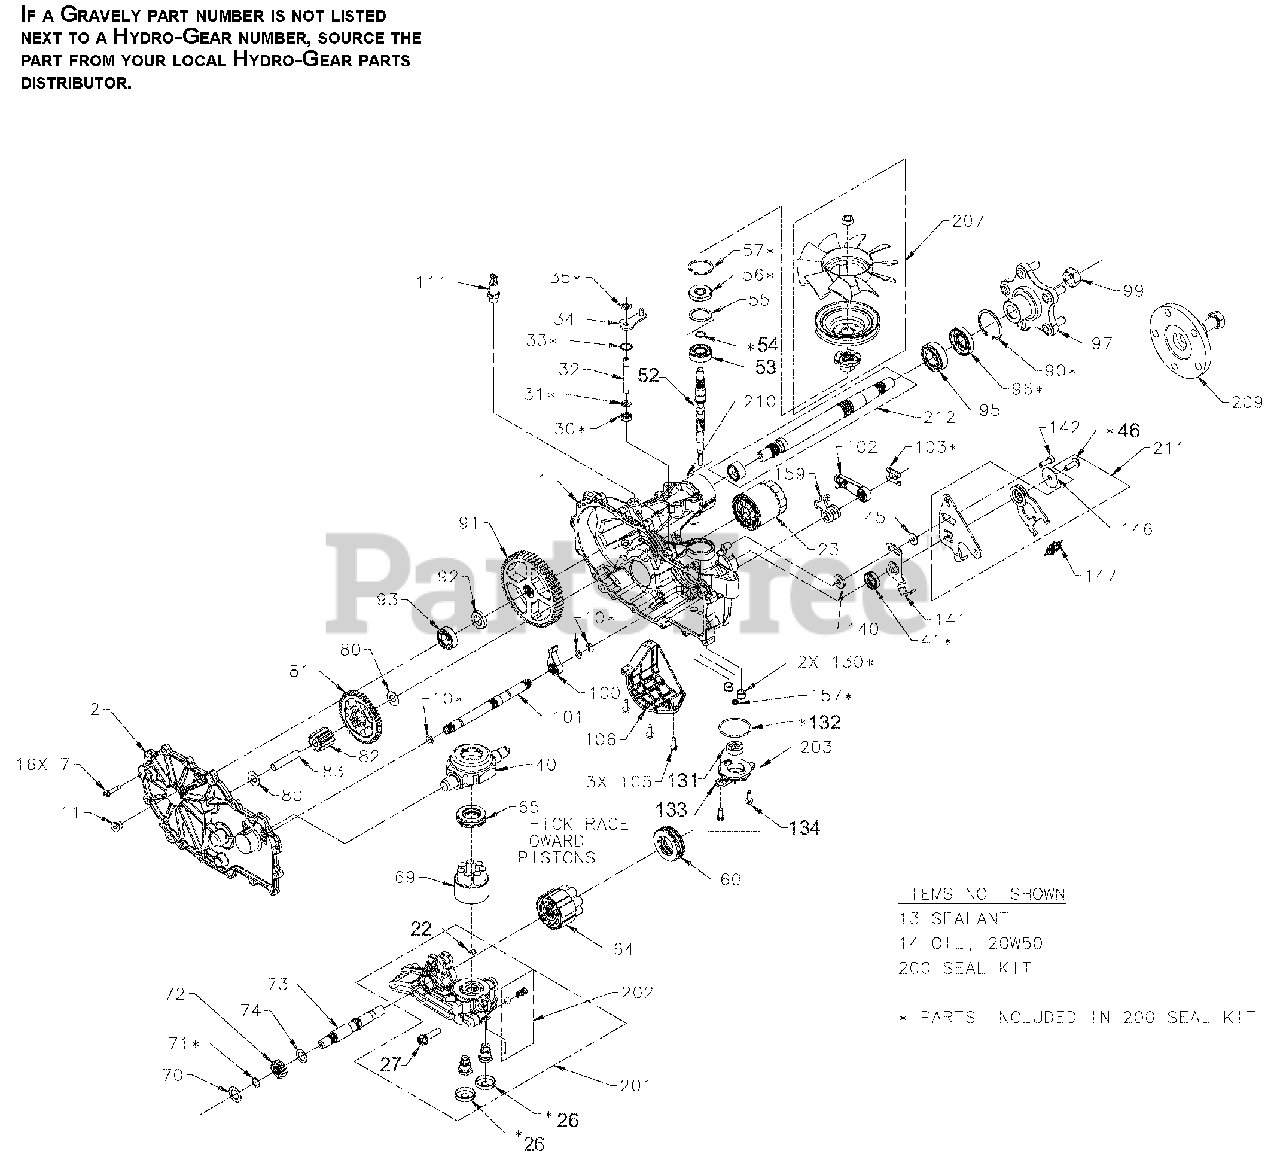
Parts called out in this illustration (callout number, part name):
7	HFHCS 1/4-20 x 1.25
11	Plug, 9/16-18 (Metal)
22	Plate, Bypass
23	Filter, Oil
26	Seal, Plug 1.25 x .25
30	Seal, Lip .375 x .75 x .25
31	Ring, Retention .375 External
33	Ring, Retention .750 Internal
34	Arm, Bypass
35	Ring, Retention .375 Ext
40	Trunnion, Swashplate
41	Seal, LIP 18 x 32 x 7
45	Washer, .34 x .88 x .06
46	TWHCS 5/16-24 x 1.00
53	Bearing, Ball 17 x 40 x 12 Open 6203
54	Ring, Ret Wire .561 ID
55	Washer, 1.23 x 1.56 x .04
56	Seal, Lip 17 x 40 x 7
57	Ring, Ret 1.59 Int
60	Bearing, Thrust
64	Assembly, Cylinder Block, 16cc
65	Bearing, Thrust Ball 30 x 52 x 13
69	Assembly, Block, 7 Piston
70	Washer, .63 x 1.0 x .05
71	Ring, Retaining .625
74	Washer, .72 x 1.16 x .04
80	Washer, .5 x 1.0 x .03
83	Jack Shaft
90	Ring, Ret 2.06 Int
95	Bearing, Ball 1.0 x 52 x 15 Open 6205M
96	Seal, Lip 25 x 52 x 10 TC (Gray)
97	Kit, Hub, 4 Bolt
99	Nut, Hex Lock 3/4-16
102	Brake Handle
103	Clip, Retaining
105	HFHCS 1/4-20 x .75
106	Guard, Filter, RH
111	Fitting, Str 9/16-18 SAE .5 Barb
131	Assembly, Gerotor Tang x 1.15 x .39
132	O-Ring, -137, 0.103 x 2.05
134	HFHCS 1/4-20 x .75
140	Spacer, .320 x 1.00 x .179
141	Arm, Neutral Left
142	SHCS 5/16-24 x 1 Patch
146	Washer, .343 x 1.5 x .062
147	Spring, Extension Rtn - 34 lbs
159	Spring, Torsion CCW
200	Kit, Seal ( * - parts included in this kit)
207	Kit, Fan and Pulley
210	Kit, Input Shaft (includes items 52, 53 and 54)
NS	Sealant
